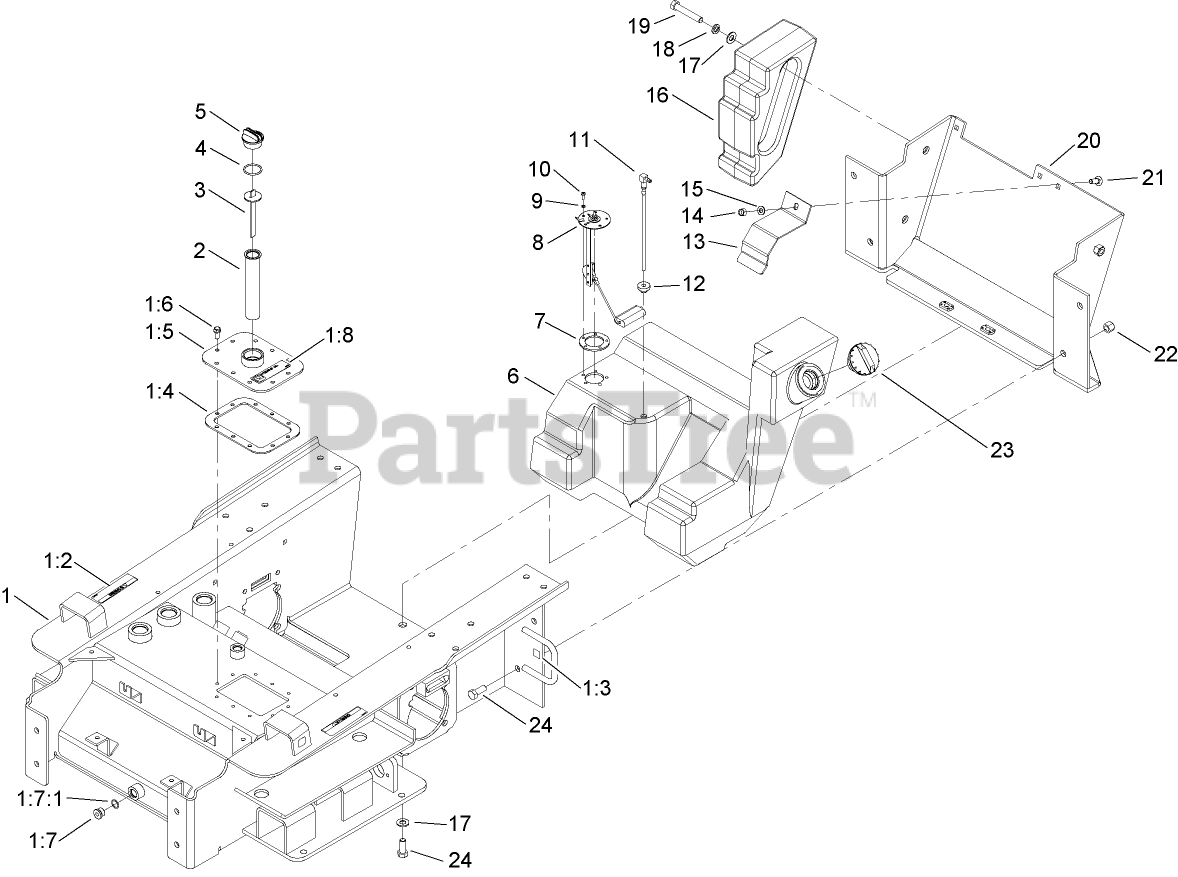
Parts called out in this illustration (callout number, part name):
1	CHASSIS ASM
1:2	DECAL-PINCH
1:3	DECAL-POINT, LIFT
1:4	GASKET-COVER, ACCESS
1:5	TANK COVER ASM
1:6	SCREW
1:7	PLUG-HEX
1:7:1	O-RING
1:8	DECAL-OIL, HYD
2	FILTER-SCREEN
3	DIPSTICK-OIL
4	O-RING
5	PLUG-PLASTIC
6	TANK-FUEL
7	GASKET-SENDER, FUEL
8	SENDER-FUEL
9	WASHER-LOCK
10	SCREW-PPH
11	PIPE-STAND
12	BUSHING
13	CLAMP-TANK, FUEL
14	NUT-LOCK, NI
15	WASHER-FLAT
16	COUNTERWEIGHT-REAR
17	WASHER-FLAT
18	WASHER-LOCK
19	SCREW-HH
20	REAR FRAME COVER ASM
21	SCREW-CARR
22	NUT-LOCK, NI
23	CAP-FUEL
24	SCREW-HH
